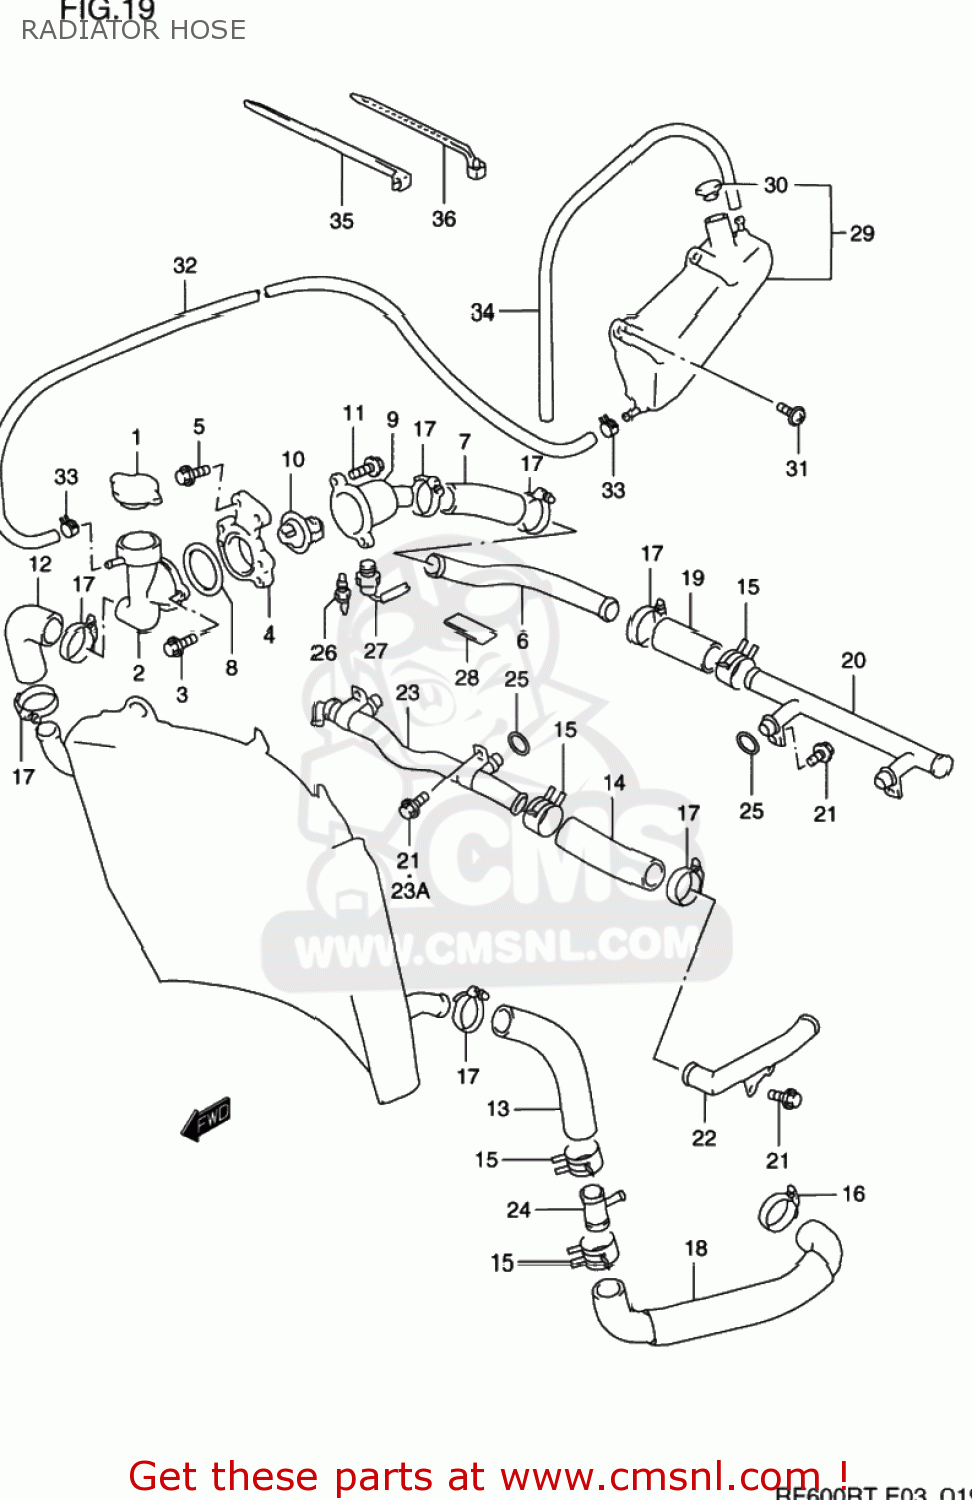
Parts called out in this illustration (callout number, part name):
1	CAP,RADIATOR
2	CONDUCTION,RADIATOR
3	BOLT
4	BRACKET,CONDUCTION
5	BOLT
6	PIPE,CONDUCTION INLET
7	HOSE,WATER
8	O RING(D:2.4,ID:43.2)
9	CONNECTOR,THERMOSTAT INLET
10	THERMOSTAT,WATER
11	BOLT
12	HOSE,RADIATOR INLET
13	HOSE,RADIATOR OUTLET
14	HOSE,WATER
15	CLAMP
16	CLAMP
17	CLAMP
18	HOSE,WATER PUMP INLET
19	HOSE,HEAD OUTLET
20	PIPE,HEAD OUTLET
21	BOLT 6X12
21A	BOLT
21B	BOLT
22	PIPE
23	PIPE,CYLINDER INLET
24	UNION,HOSE JOINT
25	O RING(D:3.2,ID:17.8)
26	GAUGE ASSY,WATER TEMP
27	SWITCH COMP,RADIATOR FAN
28	CUSHION(50X42X2.0)
29	TANK ASSY,RESERVOIR
30	CAP,RESERVOIR TANK
31	SCREW(6X20)
32	HOSE,RESERVOIR TANK INLET
33	CLIP
34	HOSE,RESERVOIR TANK INLET
35	CLAMP
36	CLAMP L:165
